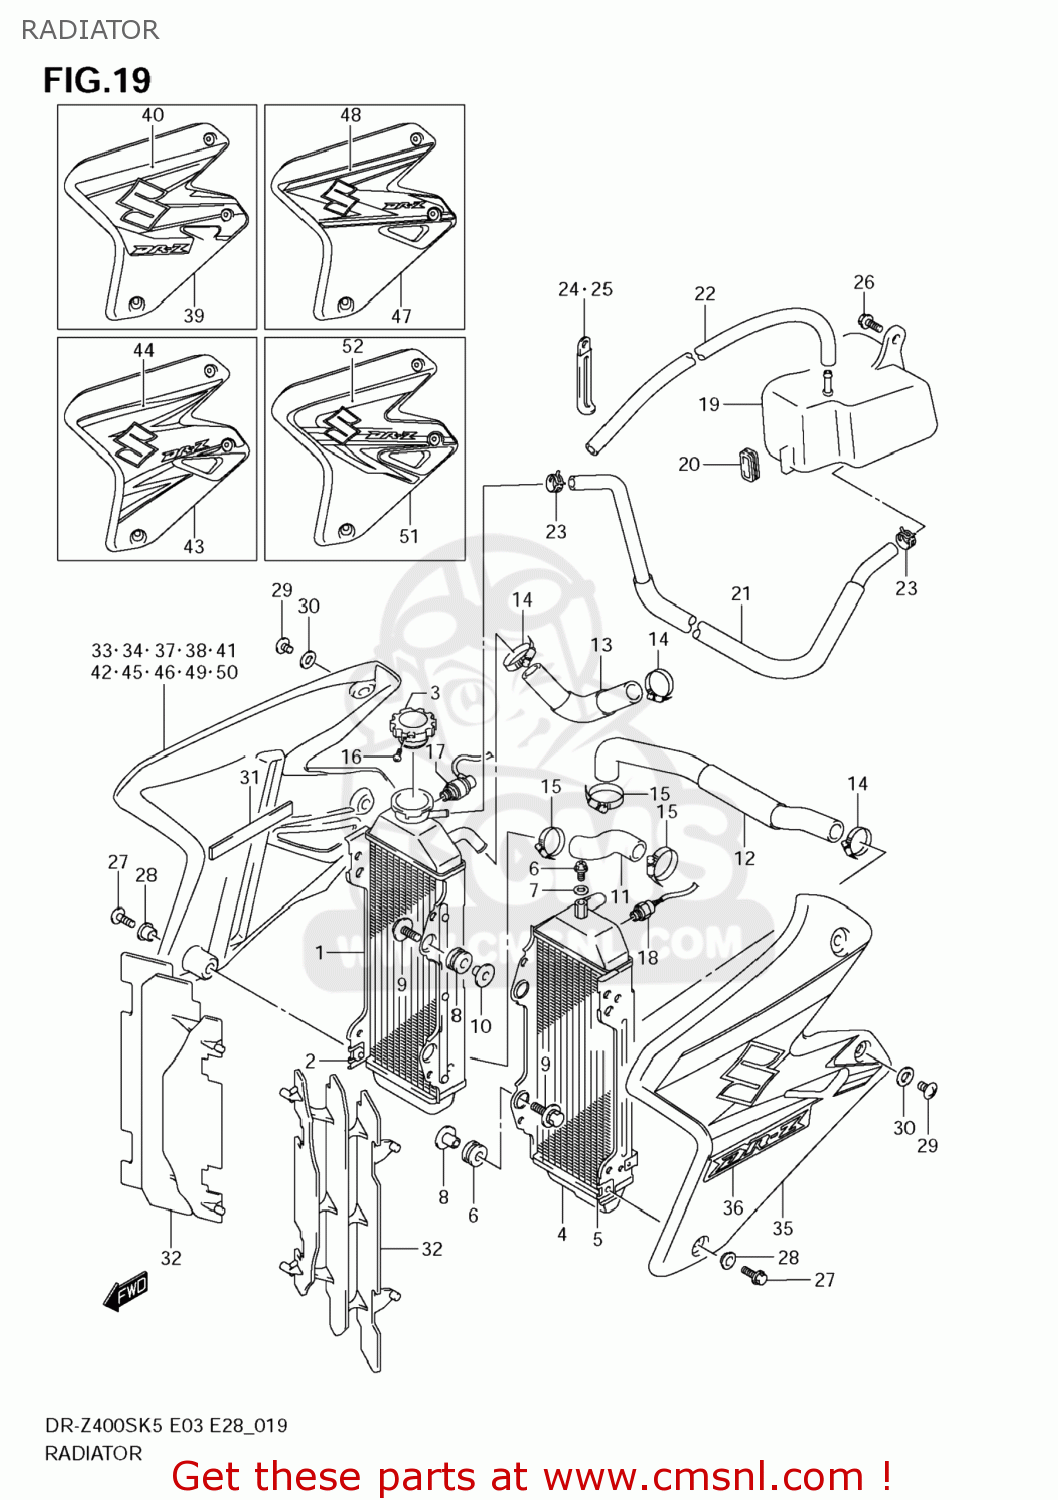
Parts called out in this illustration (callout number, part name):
1	RADIATOR COMP,
2	NUT
3	CAP,RADIATOR(1.1)
4	RADIATOR COMP,
5	NUT
6	UNION BOLT,AIR VENT
7	GASKET(6.4X11.5X0.8) (NAS)
8	CUSHION,RADIATOR LWR
9	BOLT(6X25)
10	SPACER(6.5X10.5X14.1)
11	HOSE,RADIATOR INLET
12	HOSE,RADIATOR OUTLET
13	HOSE,RADIATOR JOINT
14	CLAMP
15	CLAMP
16	SCREW,RADIATOR CAP
17	SWITCH ASSY,WATER TEMP
18	SWITCH,FAN
19	TANK,RESERVOIR
20	CUSHION,RESERVOIR TANK
21	HOSE,RESERVOIR TANK INLET
22	HOSE(5X9X2000)
23	CLIP
24	CLAMP(L:45 T:0.6)
25	CLAMP(L:45)
26	BOLT
27	SCREW
28	WASHER
29	SCREW
30	WASHER
31	CUSHION,TOOL HOLDER
32	LOUVER,RADIATOR
33	COVER,RADIATOR,R(BLUE)
34	TAPE,RADIATOR COVER,R
35	COVER,RADIATOR,L(BLUE)
36	TAPE,RADIATOR COVER,L
37	COVER,RADIATOR,R(BLUE)
38	TAPE,RADIATOR COVER,R
39	COVER,RADIATOR,L(BLUE)
40	TAPE,RADIATOR COVER,L
41	COVER,RADIATOR,R(BLUE)
42	TAPE,RADIATOR COVER,R
43	COVER,RADIATOR,L(BLUE)
44	TAPE,RADIATOR COVER,L
45	COVER,RADIATOR,R(BLUE)
46	TAPE,RADIATOR COVER,R
47	COVER,RADIATOR,L(BLUE)
48	TAPE,RADIATOR COVER,L
49	COVER,RADIATOR,R(BLACK)
50	TAPE,RADIATOR COVER,R
51	COVER,RADIATOR,L(BLACK)
52	TAPE,RADIATOR COVER,L
